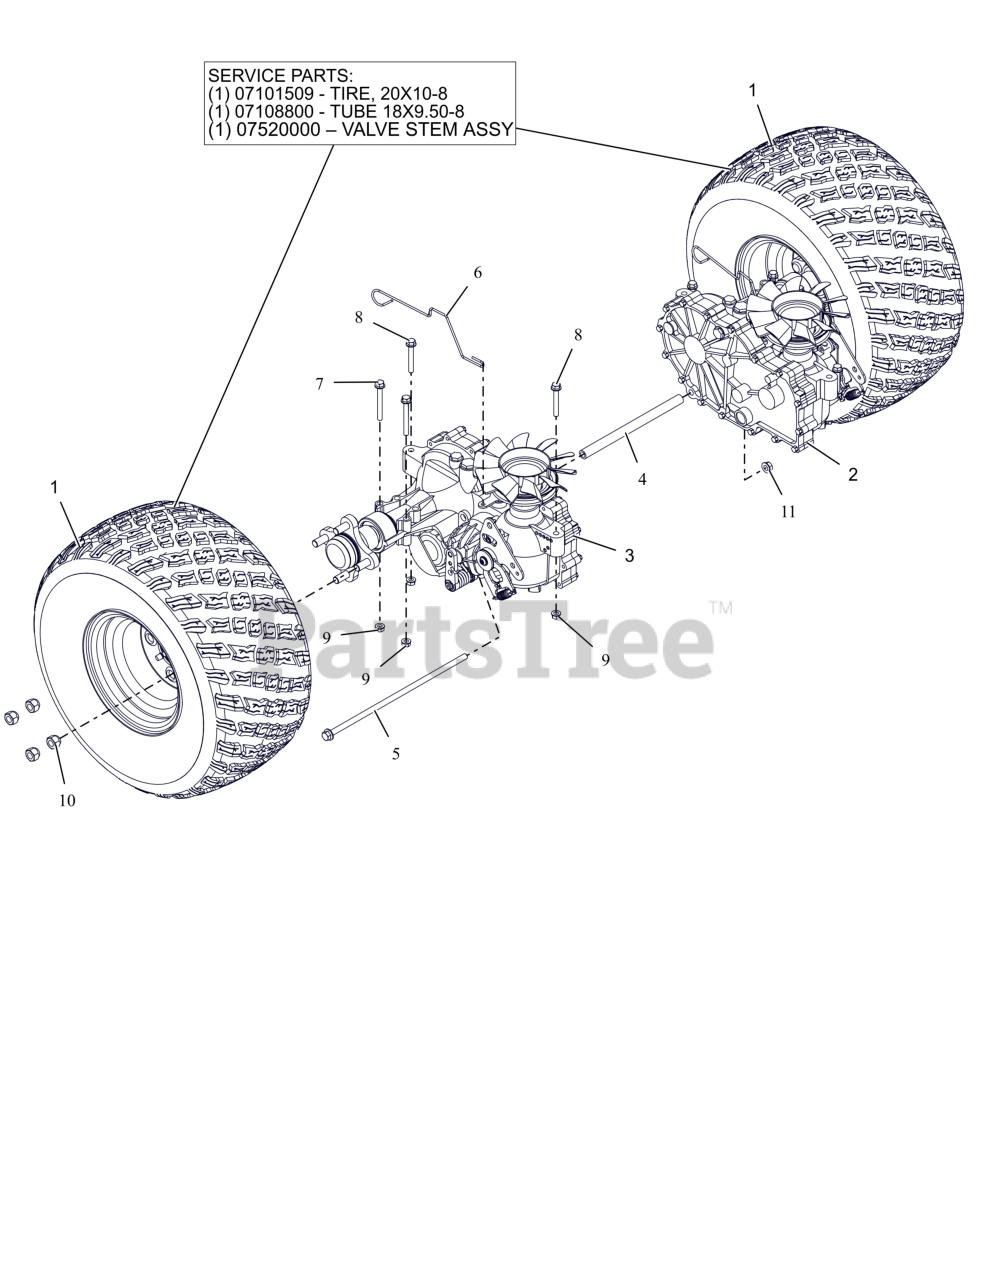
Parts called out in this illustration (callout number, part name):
1	ASM- TIRE/WHL 20X10-8
2	TRANSAXLE- ZT2800 - LH
3	TRANSAXLE- ZT2800 - RH
4	SPCR, TRANSAXLE .406 ID X .630 OD X 9.27 (BLACK)
5	BLT, HEX-FLG 0.375-16X13 GR5 ZC120
6	WIRE- DUMP VALVE LEVER
7	BLT,HEX-FLG .31-18X2.75 G5 ZCC
8	BLT,HEX-FLG .31-18X2.25 G5 ZCC
9	NUT,LK-CTR-FLG .31-18 GF ZCC
10	NUT, WHEEL .50-20 ZCC
11	NUT-LK-CTR-FLG .375-16 GF ZCC
